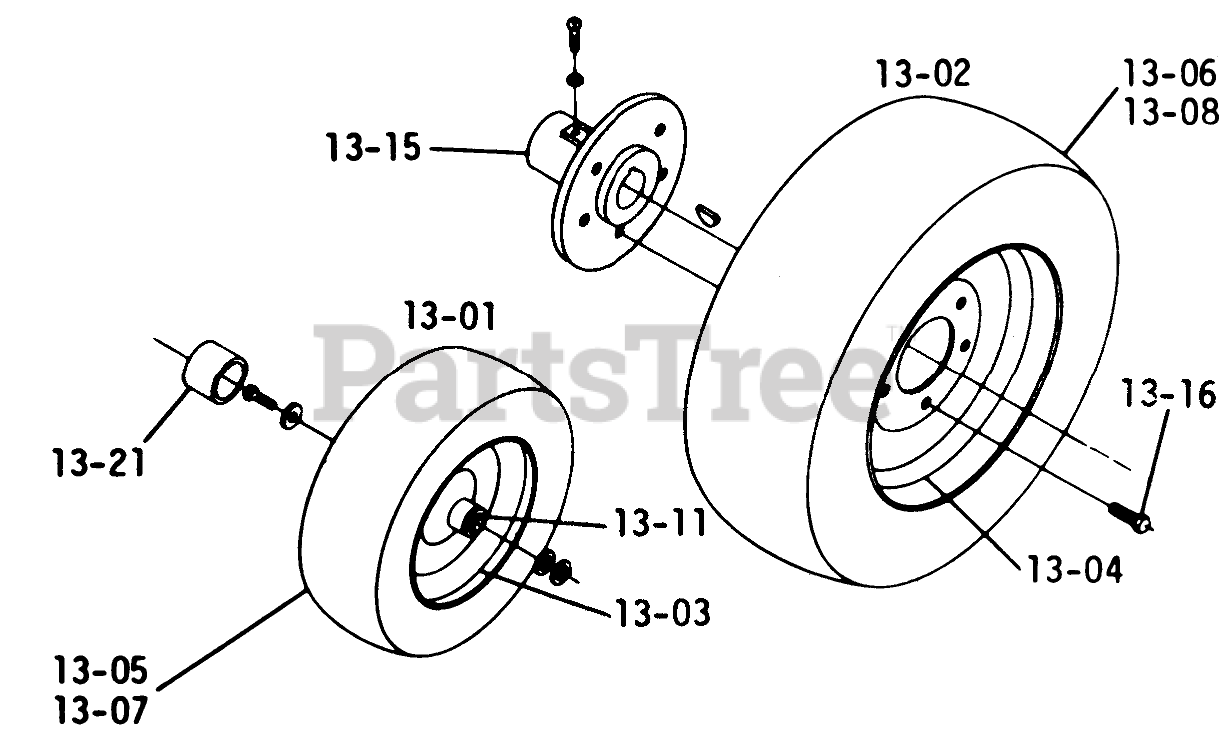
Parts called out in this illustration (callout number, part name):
13-01	Wheel-Complete
13-02	Wheel and Tire
13-03	WHEEL
13-04	Wheel
13-05	TIRE TURF SAVER 16X6.50-8
13-06	Tire
13-07	Tube
13-08	TUBE-INNER
13-11	Bearing
13-15	Hub Wheel
13-16	Lug Nut
13-21	HUB CAP
